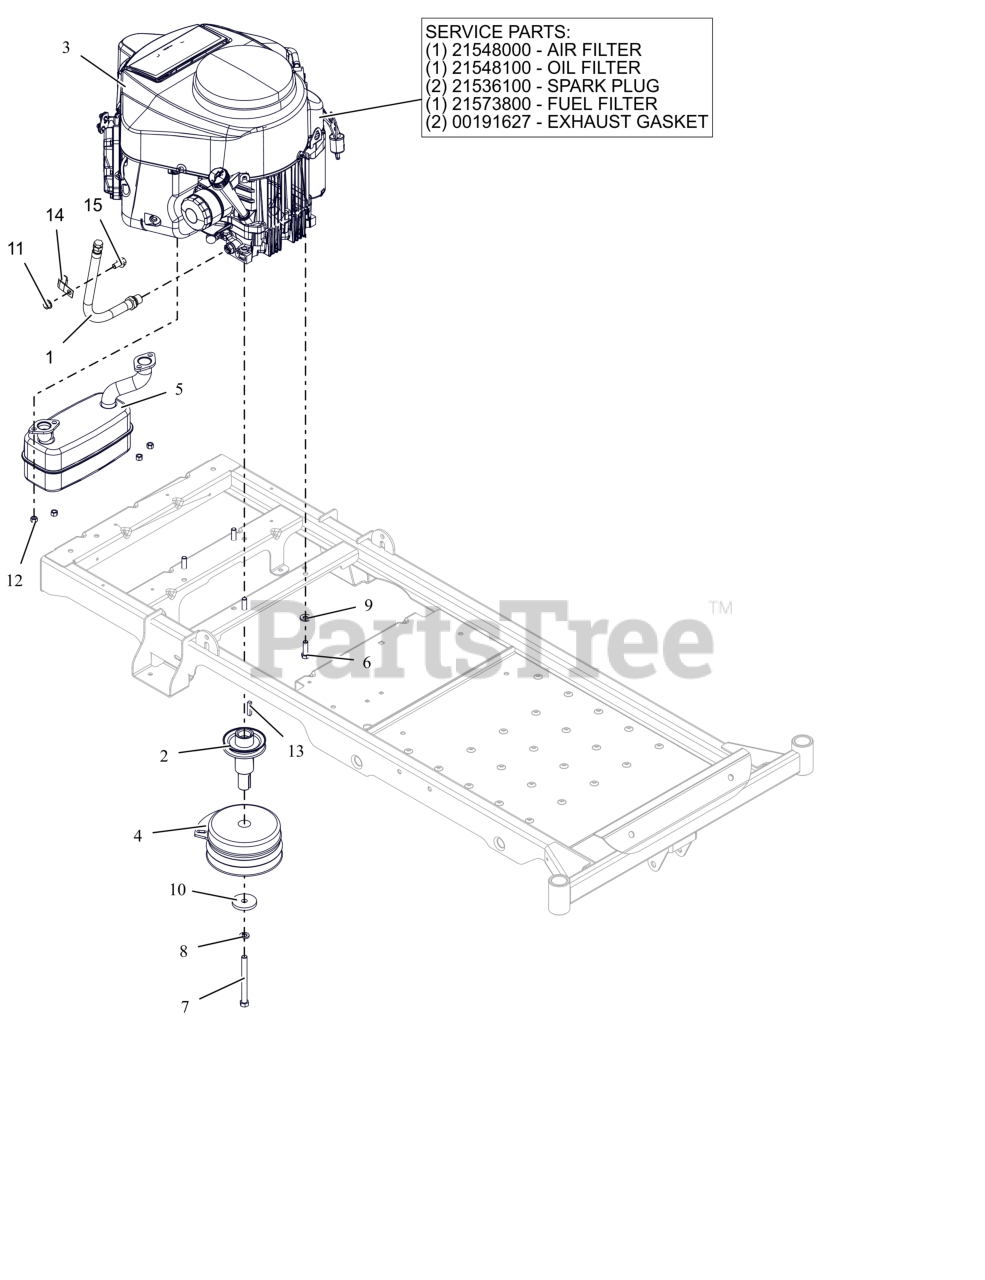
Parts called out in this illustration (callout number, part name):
1	HOSE, OIL DRAIN
2	WLDMT, CRANKSHAFT EXTENSION
3	ENGINE, KAWASAKI FR651V
3	AIR FILTER, KAWASAKI FR
3	OIL FILTER, KAWASAKI FR
3	PLUG, SPARK
3	FUEL FILTER-KAWASAKI FR
3	GASKET, MUFFLER S/O
4	CLUTCH, 105 FT*LB MONO POLE
5	MUFFLER, KAWI TWIN
6	BLT, HEX .38-16X1.25 G5 ZCC NT
7	BLT, HEX .44-20X4.50 G8 ZCC NT
8	WSHR, LK-REG .438X.109 ZCC
9	WASHER, 3/8" SPRING DISC
10	WSHR, FLT .469X2.00X.250 ZCC
11	NUT-LK-CTR-FLG .375-16 GF ZCC
12	NUT-LK-TOP-FLG M8 ZCC
13	KEY-SQ .25 X 1.25 X .25 SAE
14	J-CLAMP
